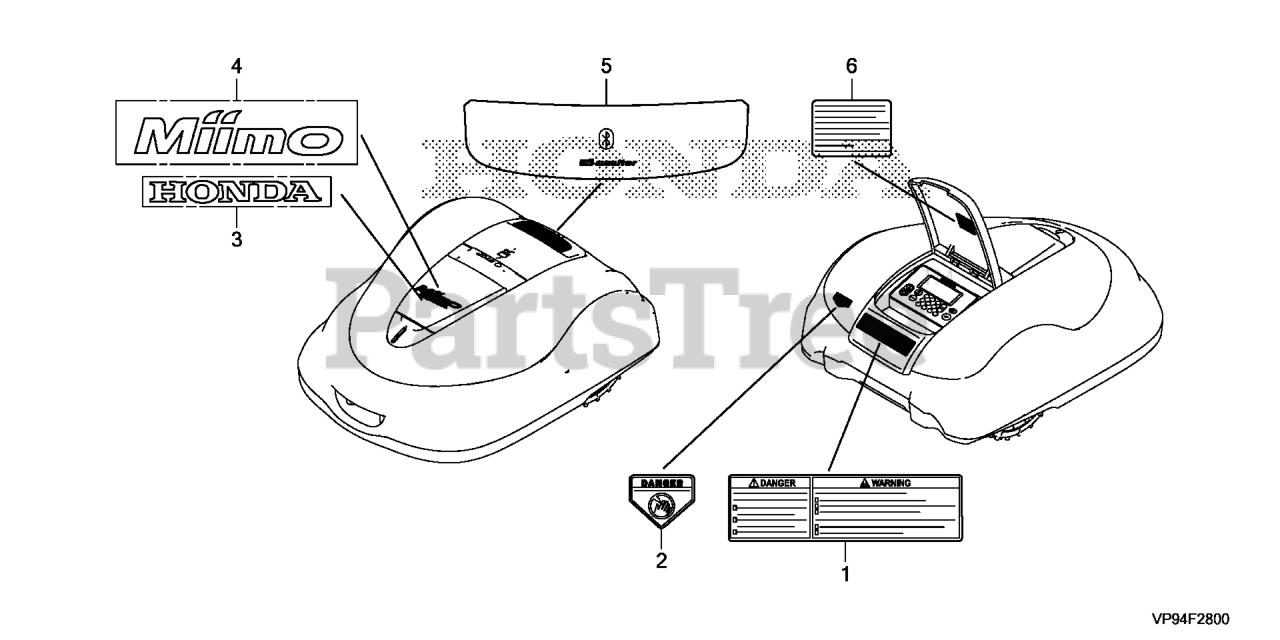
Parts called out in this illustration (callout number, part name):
1	MARK, CAUTION (US)
2	MARK, DANGER
3	MARK, HONDA
4	MARK, EMBLEM
5	MARK, MII-MONITOR
6	MARK, FCC TEXT
